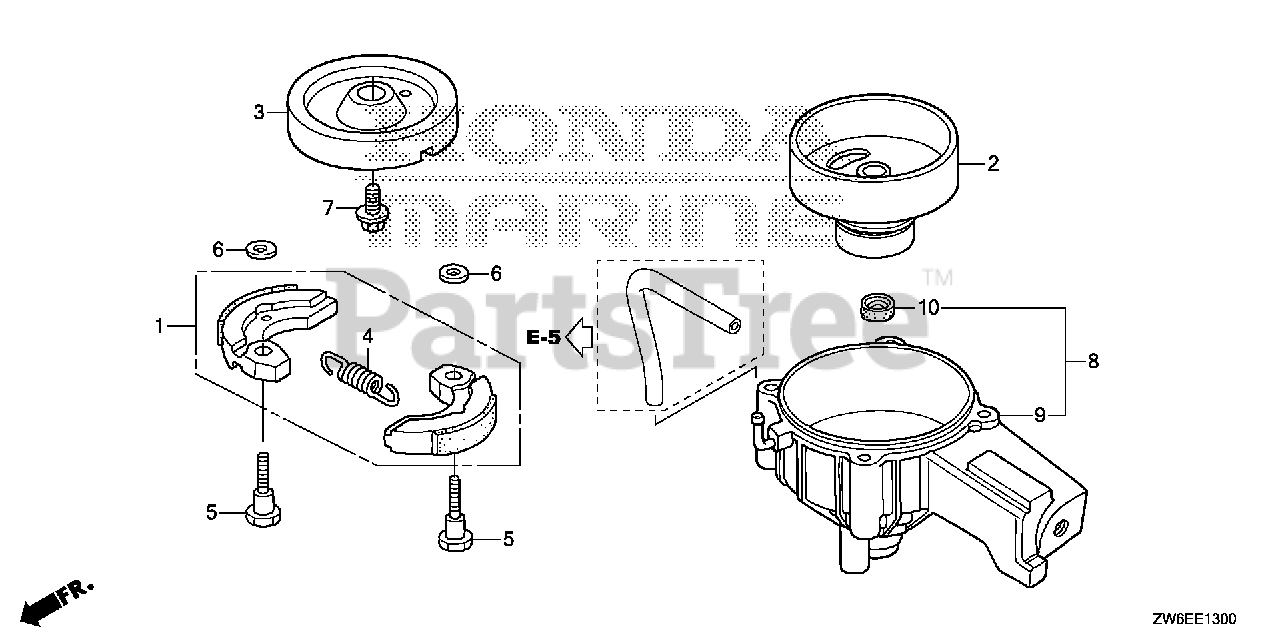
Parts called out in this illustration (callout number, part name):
1	CLUTCH ASSY.
2	CLUTCH OUTER ASSY.
3	STAY, CLUTCH
4	SPRING, CLUTCH SHOE
5	BOLT, CLUTCH (8MM)
6	WASHER, PLAIN (8MM)
7	BOLT, CLUTCH STAY (8MM)
8	HOUSING ASSY., CLUTCH
9	HOUSING, CLUTCH
10	SEAL, WATER (11X21X8)
